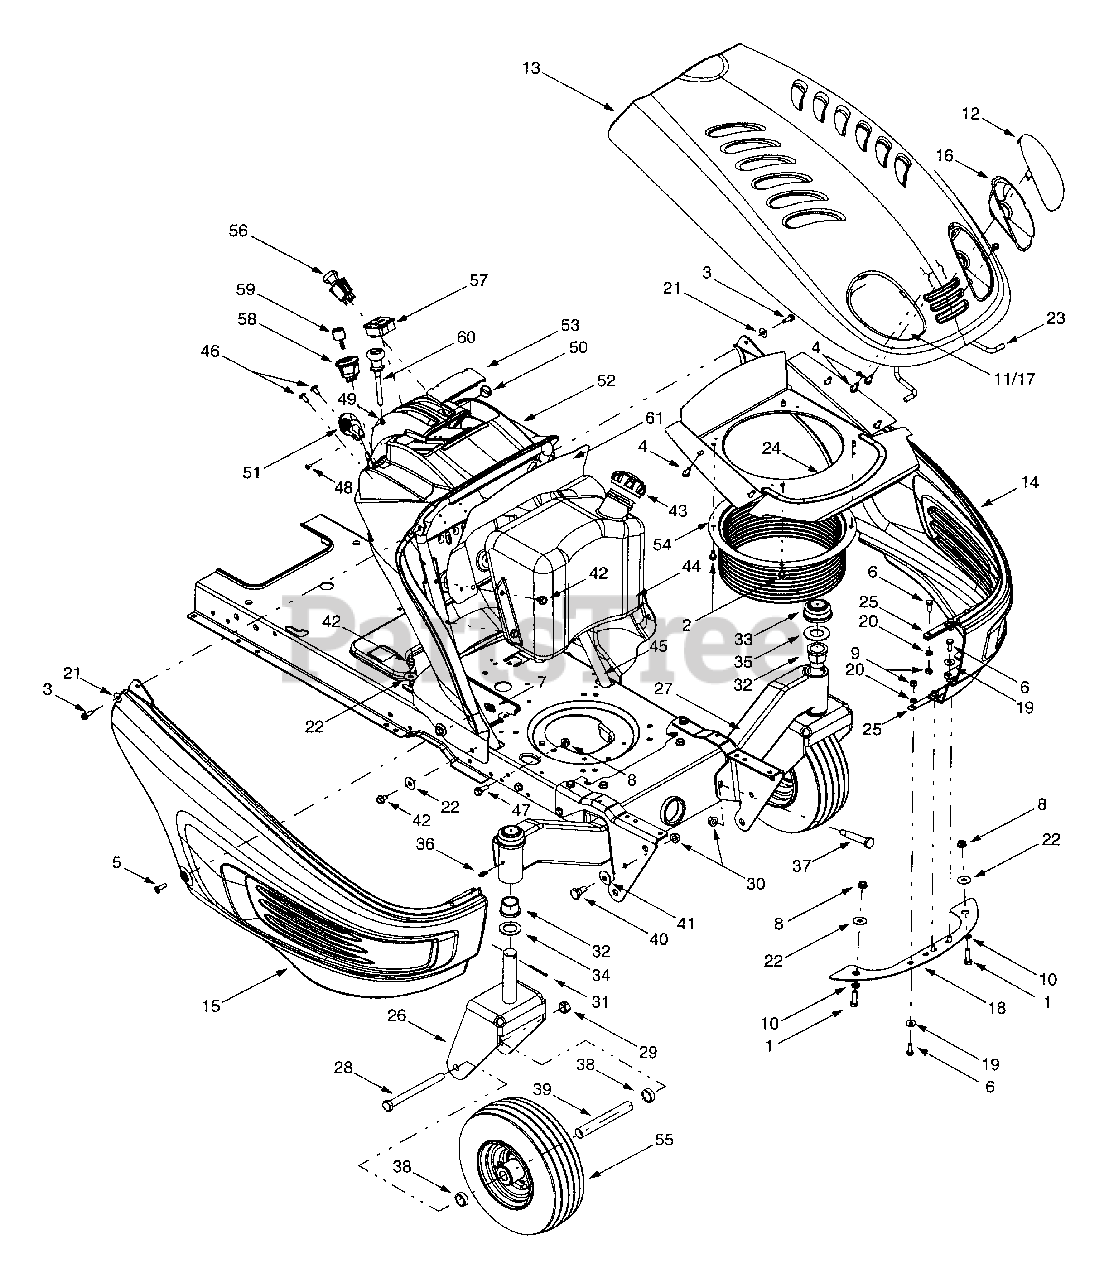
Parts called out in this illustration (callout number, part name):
1	Hex Cap Screw, 5/16-18 x 1.0
2	Self-tapping Screw, 1/4-20 x .5
3	Self-tapping Screw, 1/4-20 x .75
4	Self-tapping Screw, 1/4-15 x .75
5	Pan Phillips Screw, 1/4-20 x .75
6	Hex Cap Screw, 1/4-20 x .75
7	U-type Speed Nut, 1/4-20
8	Flange Lock Nut, 5/16-18
9	Hex Nut, 1/4-20
10	Speed Nut
11	RH Head Light Lens
12	LH Head Light Lens
13	Hood, 4-style (Yellow)
14	LH Side Panel, 4-style (Yellow)
15	RH Side Panel, 4-style (Yellow)
16	LH Head Light Reflector
17	RH Head Light Reflector
18	Heat Shield
19	Flat Washer, .28 x .74 x .063
20	Lock Washer, 1/4
21	Flat Washer, .283 x .75 x .030
22	Flat Washer, .349 x 1.0 x .063
23	Hood Support Rod
29	Hex Lock Nut, 1/2-20
30	Flange Lock Nut, 3/8-16
31	Cotter Pin, .125 x 1.5
32	Flange Bearing
33	Plastic Cap
34	Flat Washer, 1.031 x 1.620 x .095
35	Flat Washer, 1.010 x 2.0 x .065
36	Grease Fitting, 1/4-28
37	Shoulder Screw, .50 x 2.23, 3/8-16
38	Spacer, .790 x .347
39	Wheel Spacer
40	Shoulder Screw, 3/8-16
41	Bell Washer, .39 x 1.13 x .062
42	Self-tapping Screw, 16-18 x .625
43	Fuel Tank Cap
44	Fuel Tank, Two-gallon
47	Hex Head Washer Screw, 5/16-18 x .875
48	Torx Screw, #8-32 x .375
49	Hex Nut, 8-32
50	Cap Plug, .812
51	Throttle Control Lever
52	Dash Panel
53	Dash Cap
54	Intake Bellow (Intek Single)
55	Wheel Assembly, 11 x 4 x 5 (Yellow Rim)
56	Electric PTO Switch
57	Systems Indicator Monitor/Hour Meter
58	Ignition Switch
59	Ignition Key w/ Plastic Cover
60	Choke Control/Cable
